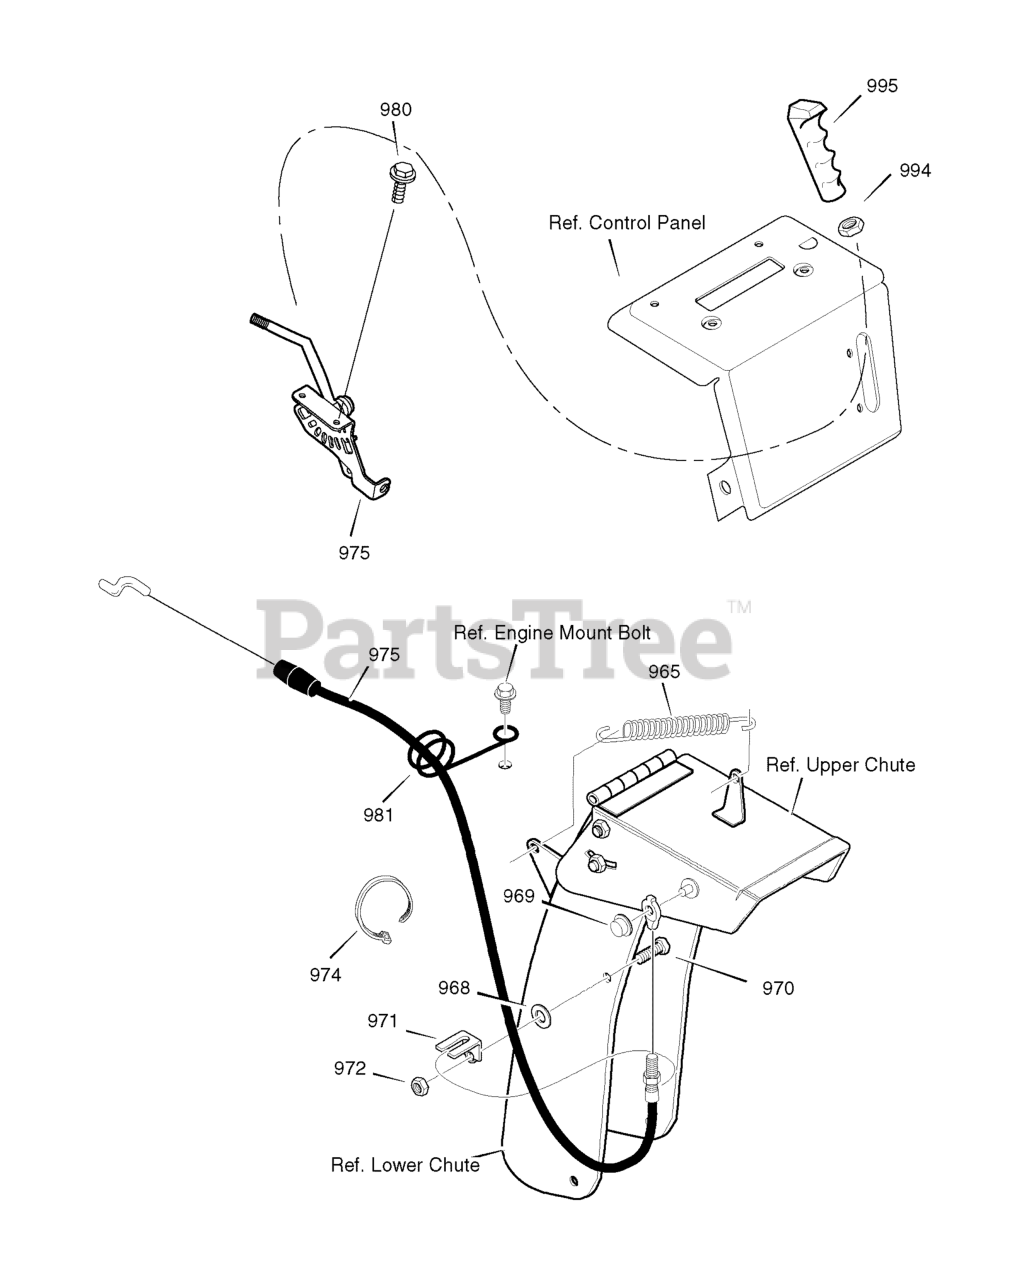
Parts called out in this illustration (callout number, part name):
965	TENSION SPRING
968	FLATWASHER
969	PUSH NUT
970	SCREW, 5/16-18 X 0.75
971	BRACKET, CABLE CHUTE
972	NUT, 5/16-18
974	TIE, CABLE
975	LEVER & CABLE, CHUTE DEFLECTOR
980	SCREW
981	WIRE FORM, CHUTE CABLE
994	NUT, 3/8-16
995	KNOB, SHIFT
